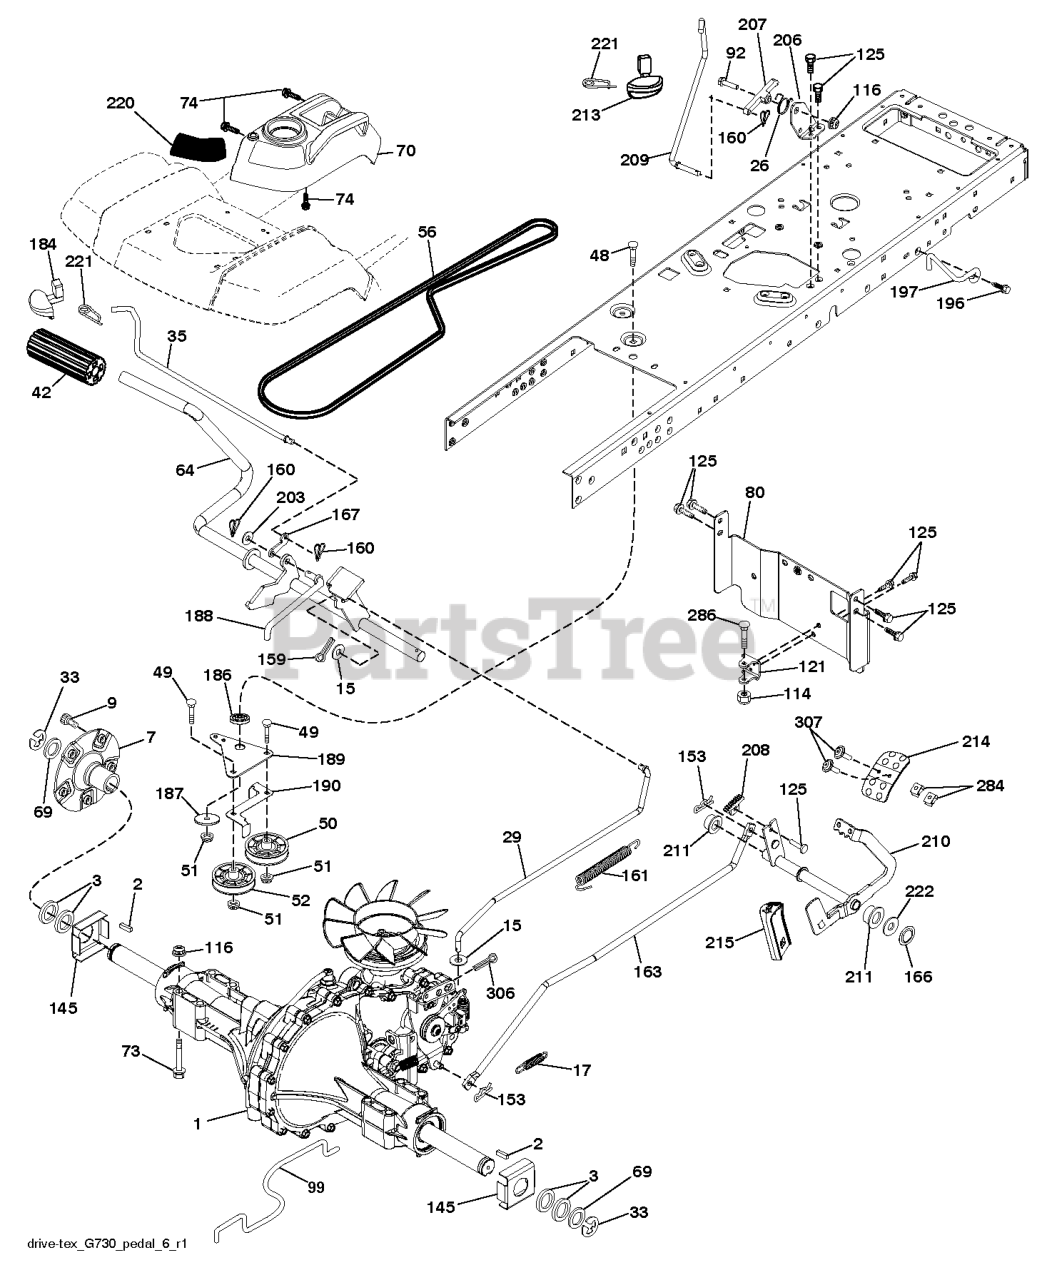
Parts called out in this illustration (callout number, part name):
2	KEY 1/4 X 2.5
7	HUB.ASM.WHEEL.REAR.23"TEX
9	HUB BOLT
15	WASHER
17	SPRING.BRAKE.HG3000/3500
26	SPRING.RETURN.CRUISE
33	E RING HYT
35	ROD .BRAKE. PARKING. GT. HUSQ.
42	PEDAL COVER T
48	BOLT.3/8-16X1.50
50	IDLER.FLAT.910.OFFSET
51	NUT LOCK FLG 3/8-16 UNC
52	IDLER.V-GROOVE.910.OFFSET
56	V-BELT.GROUND.DRIVE.
64	SHAFT.ASM.PEDAL.BRK.CNTR
70	CONSOLE.ASM.RH.GT.FC.HUSQ
73	BOLT HEX FLGHD 5/16-18X3 GR. 5
74	SCREW.HI-LO.CONSOLE
80	STRAP.TORQUE.YT.G700
92	BOLT
99	SPRING.BYPASS.YT.G700
114	NUT.71038.31-18.HEX.NYLOCK
116	NUT LOCK HEX FLANGE 5/16-18
121	BRACKET STRAP TORQUE
125	SCREW
145	WASHER.AXLE.FLANGE.HG-3000
153	RETAINER M
159	COTTER PIN
160	RETAINER CLIP
161	SPRING, RETURN LT
163	ROD PEDAL CONTROL
166	NUT.PUSH.625
167	LATCH.BRAKE.SPRING
184	RB HANDLE.PARKG.BRK.HUS/PRED
186	SPACER.RETAINER
187	WASHER 12/32X2X10GA
188	RP.LINK.CLUTCH.GROUND.DRIVE
189	BELLCRANK.GROUND.DRIVE.TRAPPED
190	KEEPER BELLCRANK ROUND DRIVE
196	SCREW 3/8-16X1
197	BRKT.ANIT-ROTATION.CLUTCH
203	WASHER
206	BRACKET.MOUNT.CRUISE.LATCH
207	LATCH.CONTROL.CRUISE
208	GEAR.SECTOR.CONTROL.CR
209	ROD.CONTROL.CRUISE.GT.
210	ROCKER.ASM.PEDAL.CONTR
211	BEARING.NYLON
213	KNOB.CONTROL.CRUSIE.HU
214	PEDAL.FORWARD.HUSQVARNA.DEALER
215	PEDAL.REVERSE.TEX.GT.4
220	REFLECTOR.RH.TEX GT
221	RETAINER.SPRING.CLIP.H
222	WASHER 21/32 X 1-1/4 X 10 GA.
284	NUT.U-CHNL.1/4-20.550DP.350PNL
286	BOLT.5/16-18X2.5
306	PIN COTTER
307	SCREW.MACHINE.CR.1/4-20
